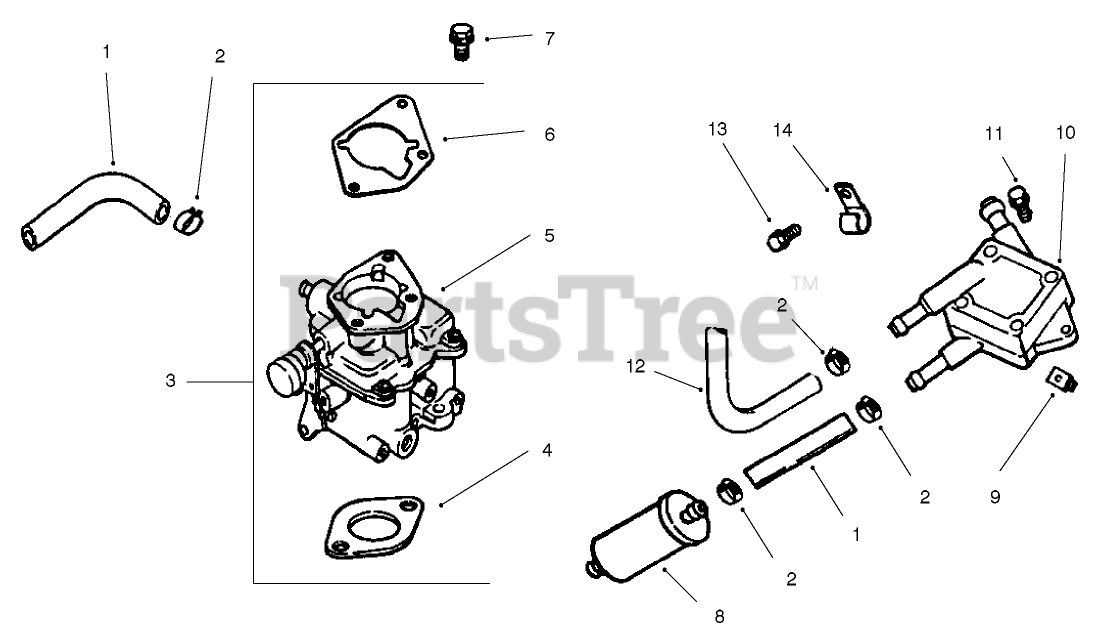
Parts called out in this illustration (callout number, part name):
1	Line-Fuel 9"
2	CLAMP-HOSE, SPRING (1/2)
3	Kit-Carburetorw/Gasket(Includes 4-6)
4	Gasket-Carburetor
5	Carburetor ASM(Includes 25 757 01-S,24 757 02-S,24 757 03-S, &24 757 07-S)
6	GASKET-BASE, AIR CLEANER
7	SCREW-FLANGE (M6X1.0X30)
8	Filter-Fuel
9	Nut-Plastic
10	PUMP-FUEL
11	SCREW-TAP (M6X1.7X18)
12	Line-Fuel, Flexible (15.5)
13	Screw-HF (M6x1.0x12)
14	CLIP-CABLE
